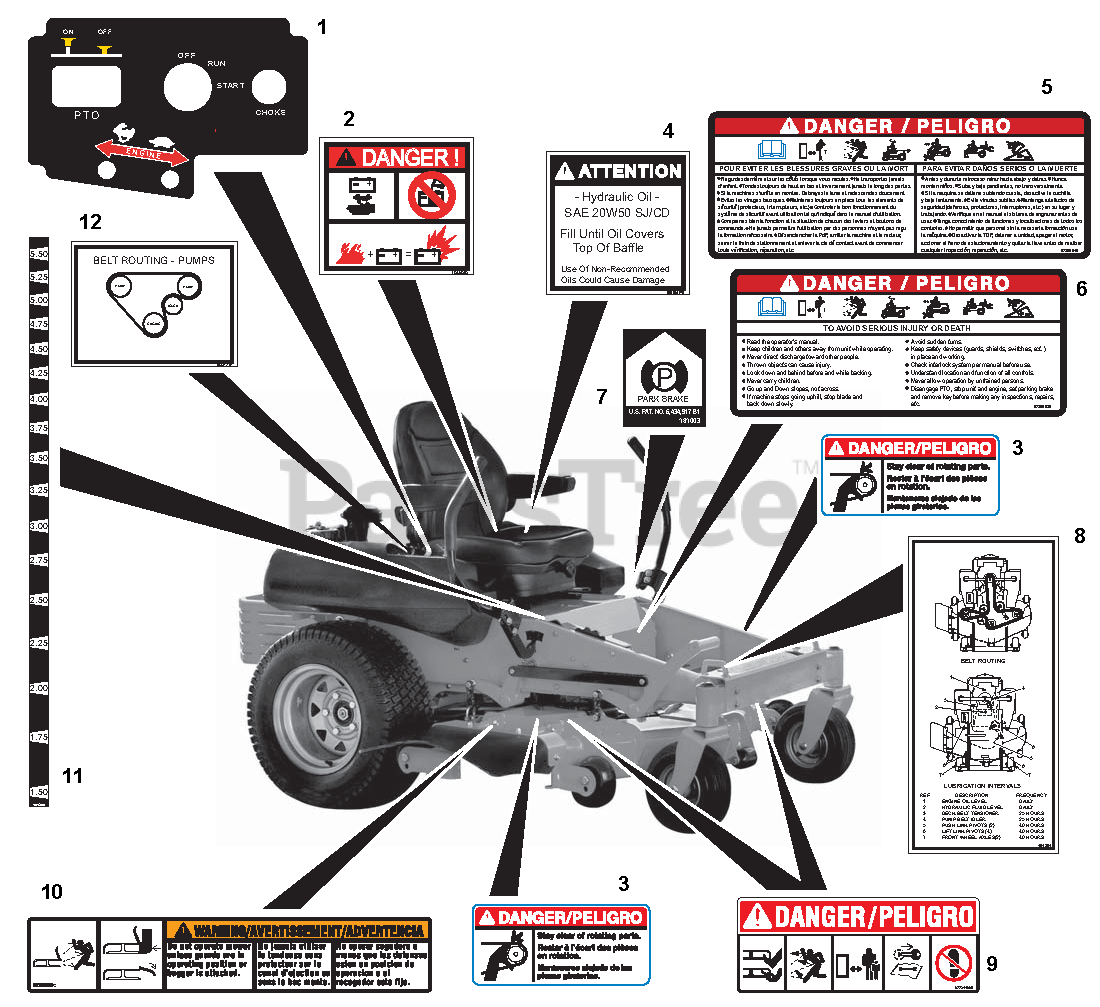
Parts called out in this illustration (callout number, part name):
1	DECAL, CONTROL PANEL
2	DECAL, DANGER - BATTERY
3	DECAL-DANGER-BELT ROTATING
4	DECAL, ATTENTION HYD. RES.
5	DECAL, SAFETY FRENCH - SPANISH
6	DECAL, SAFETY ENGLISH
7	DECAL, PARK BRAKE
8	DECAL, BELT RT & LUB INT
9	DECAL, MOWER PAN DANGER
10	DECAL, WARNING
11	DECAL, HOC INDEX
12	DECAL, PUMP BELTS
